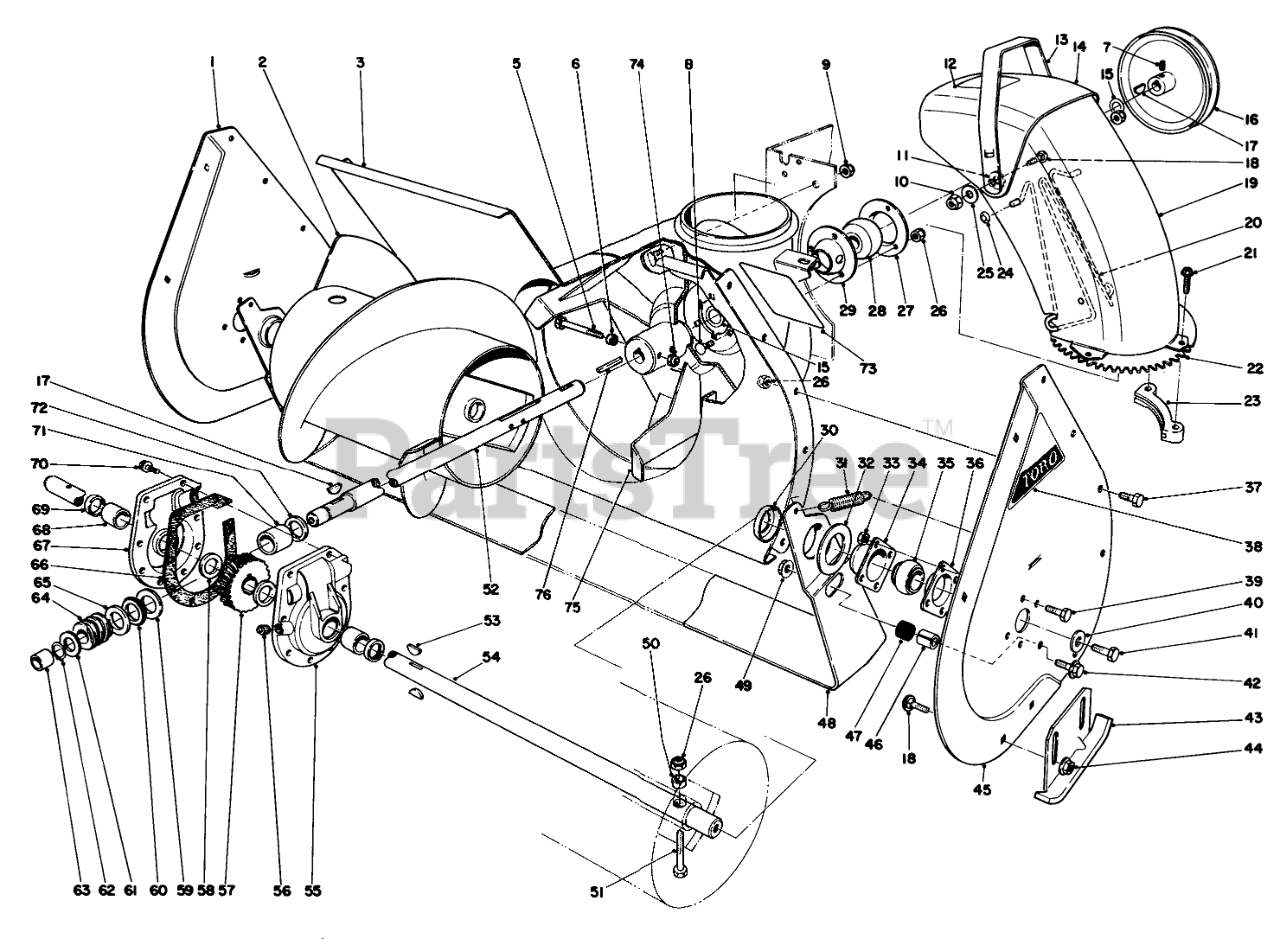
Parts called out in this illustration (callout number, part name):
1	RH AUGER SIDE PLT R
2	Auger Right
3	AUGER HSG WA RO
5	SCREW-HHF
6	SPACER
7	SCREW-SET, SQH
8	BOLT-CARR
9	NUT-LOCK, NI
10	NUT-LOCK, CONE
11	WASHER-RUBBER
12	DECAL-DANGER DISCH.
13	DEFLECTOR HANDLE B
14	Deflector Chute (Incl. Ref. #12)
15	WASHER
16	IMPELLER PULLEY
17	KEY-WOODRUFF
18	SCREW-CARR
19	CHUTE B
20	CHUTE WIRE
21	SPECIAL SCREW
22	Gear-Chute Swivel
23	CHUTE RETAINER
24	NUT-PUSH
25	WASHER-BELLEVILLE
26	NUT-LOCK, NI
27	Bearing Flange Rear
28	BEARING-BALL
29	Bearing Flange Front
30	Positioner-Scraper
31	SPRING-TENSION
32	SCRAPER BLADE SPACER
33	NUT-LOCK, CONE
34	BEARING-FLANGE, FRONT
35	BEARING
36	BEARING-FLANGE, REAR
37	SCREW-HH
38	AUGER SIDE PLT DECAL
39	SCREW-HH
40	WASHER
41	SCREW-HH
42	SCREW-HHF
43	AUGER SKID WA R
44	NUT-HHF, WHIZ
45	LH AUGER SIDE PLT R
46	SCRAPER STOP SPACER
47	SCRAPER STOP CUSHION
48	24 SCRAPER BLD
49	NUT-HF
50	SPACER-HUB, AUGER
51	Auger Bolt
52	IMPELLER SHAFT
53	KEY-WOODRUFF
54	24 AUGER SHAFT
55	Gear Case (Incl. Ref. #68 & 69)
56	PLUG-PIPE, SQH
57	GEAR-WORM, 27T
58	WASHER-THRUST
59	WASHER-THRUST
60	BEARING-THRUST
61	WASHER-THRUST
62	Ring-Snap
63	BUSHING
65	THRUST-WASHER
66	GASKET-CASE, GEAR
67	Gear Case (Incl. Ref. #68 & 69)
68	BUSHING
69	SEAL-OIL
70	SCREW-TAPTITE
71	BUSHING-SPECIAL
72	RING-QUAD
73	DECAL-WARNING, AUGER
74	NUT-LOCK, NI
75	IMPELLER WA B
